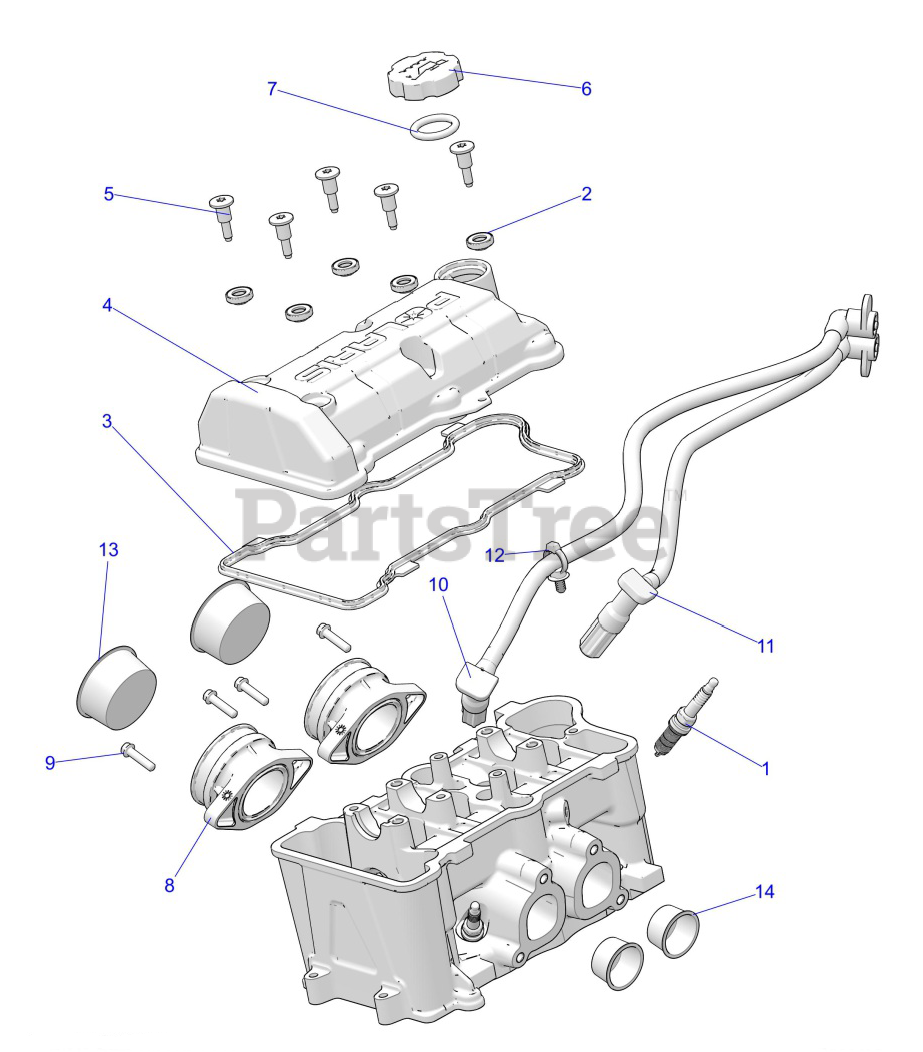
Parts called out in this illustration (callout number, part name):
1	SPARK PLUG- 12 MM
2	ISOLATOR-VALVE COVER
3	SEAL-VALVE COVER- 2 CYL- SOHC
4	COVER-VALVE-CAST-2 CYL- SOHC
5	BOLT-SHLDR-M6X12X15
6	ASM-OIL FILL CAP
7	O-RING-FILL CAP
8	ADAPTER-MANIFOLD
9	SCR-HXFLG-M6X1.0X25-10.9
10	WIRE-SPARKPLUG, MAG
11	WIRE-SPARKPLUG-PTO
12	CLIP-ROUTING
